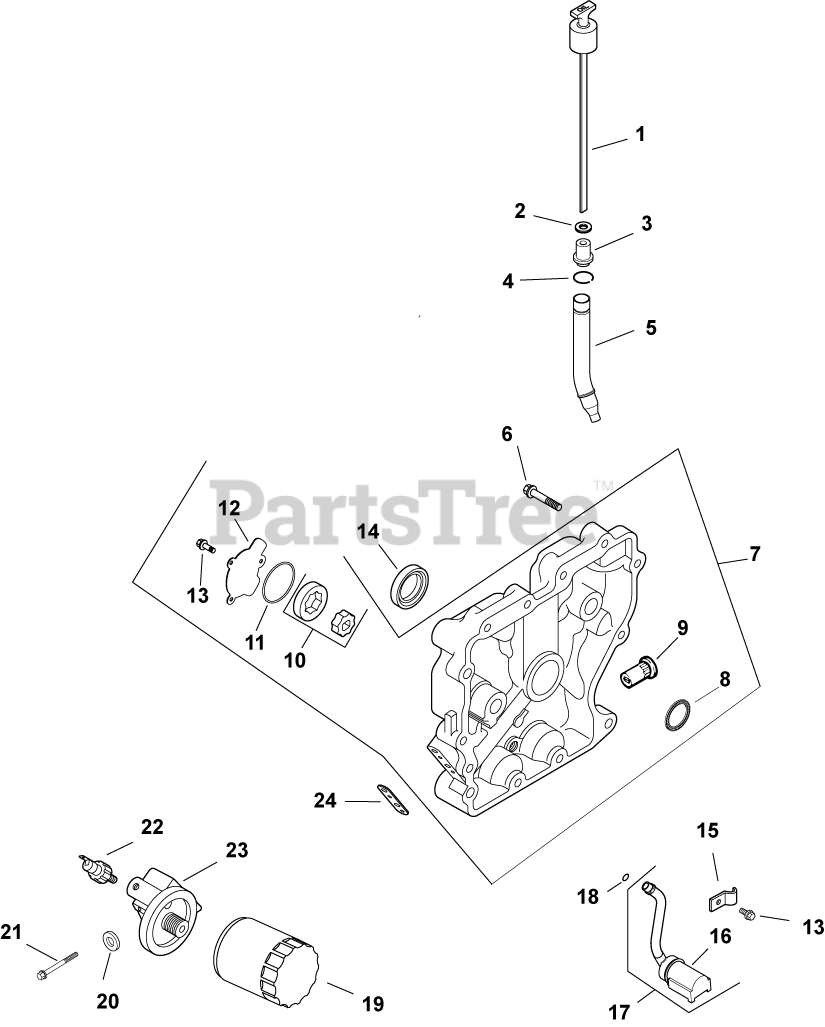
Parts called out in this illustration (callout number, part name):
3	SEAL USE 25 032 13-S
5	TUBE, OIL FILL
6	SCREW, FLG M8X1.25X45
7	CLOSURE PLATE ASSEMBLY
8	BEARING, CRANKSHAFT
9	VALVE, OIL PRESSURE RELIEF
10	PUMP ASSEMBLY, OIL
11	O-RING (1.78" DIA)
12	COVER, OIL PUMP
13	SCREW,FLG THD FRM M5X0.8X16-(#25086398S)
14	SEAL, OIL
16	PICK-UP, OIL SCREEN
17	KIT, OIL PICK-UP
18	O-RING (.5" DIA)
19	OIL FILTER
21	SCREW, FLG M6X1.0X60
22	SENSOR, OIL PSI
23	ADAPTER - DISCONTINUED
24	GASKET, OIL FILTER ADAPTER
